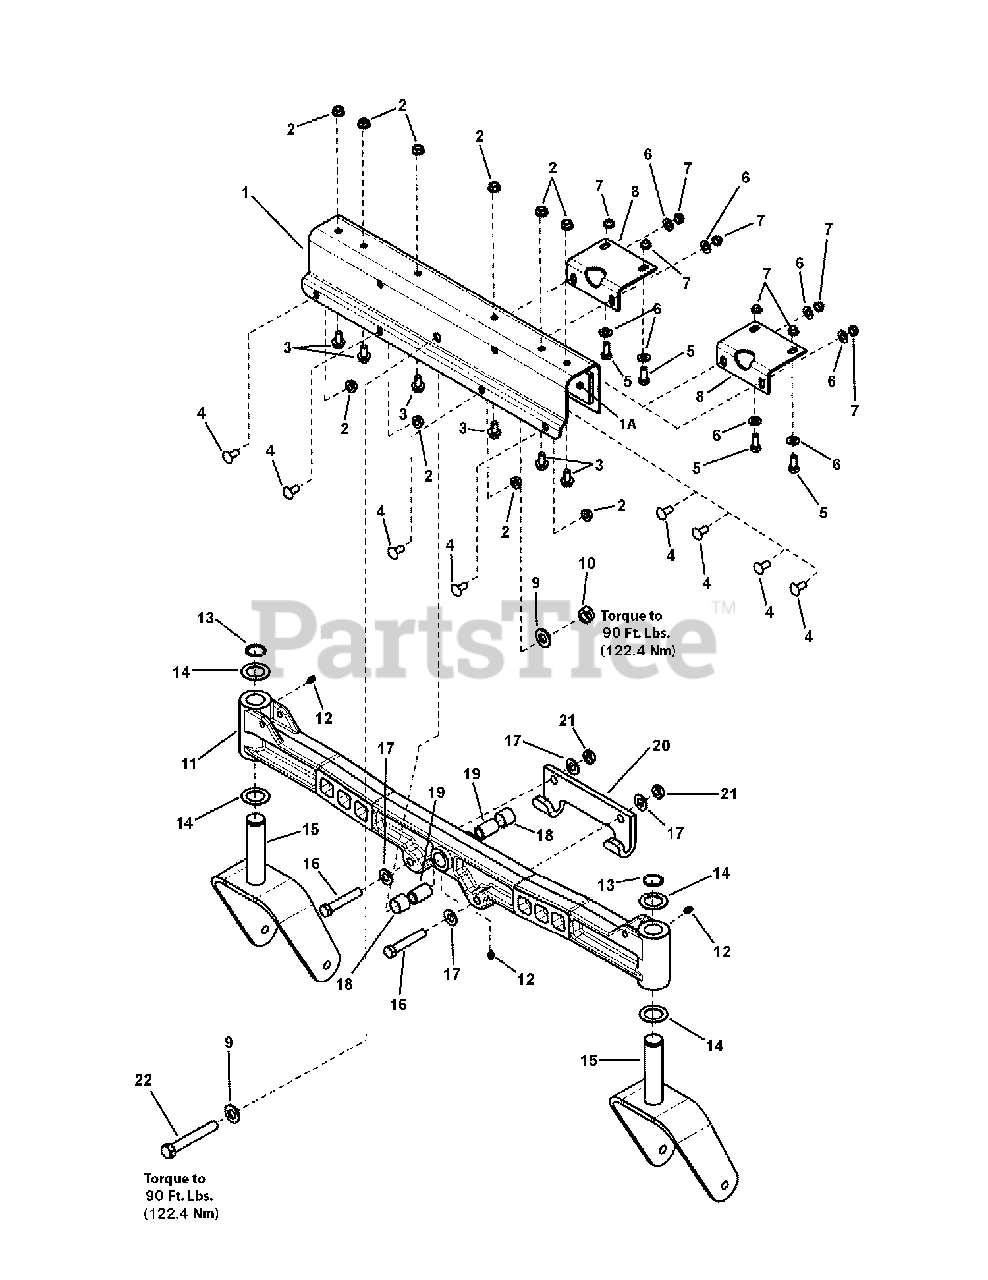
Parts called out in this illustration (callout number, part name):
1	BRACKET, Axle (Orange)
1	BRACKET, Axle (Red)
1A	PLATE, Friction, Adhesive Backed
2	NUT, 5/16-18 Flange Lock, YZ
3	BOLT, 5/16-18 x 5/8" Hex Flange lock, GR 5, YZ
4	BOLT, 5/16-18 x 3/4" Round Head Short Square Neck, GR 5, YZ
5	SCREW, 5/16-18 x 3/4" Hex Head Cap, GR 5, YZ
6	WASHER, 5/16" Flat
7	NUT, 5/16-18 Hex Top Lock, GR B
8	BRACKET, Axle Support
9	WASHER, 1/2" Flat (SAE)
10	NUT, 1/2-13 Hex Center Lock, GR 5, YZ
11	FRONT AXLE, Cast (Orange)
11	FRONT AXLE, Cast (Red)
12	LUBE FITTING, 3/16" Press Fit
13	RETAINING RING, 1" External
14	THRUST WASHER
15	CASTER YOKE & SPINDLE ASSEMBLY (Orange)
15	CASTER YOKE & SPINDLE ASSEMBLY (Red)
16	SCREW, 7/16-20 x 2-1/2", Hex Head Cap Screw, GR 5, YZ
17	WASHER, 7/16" Flat, YZ
18	BEARING, Sleeve
19	SPACER, Axle Pivot
20	HOOK, Mower, Hitch, (Orange)
20	HOOK, Mower, Hitch (Red)
21	NUT, 7/16-20 Hex Center lock Jam
22	SCREW, 1/2-13 x 3-1/2" Hex Head Cap, YZ
